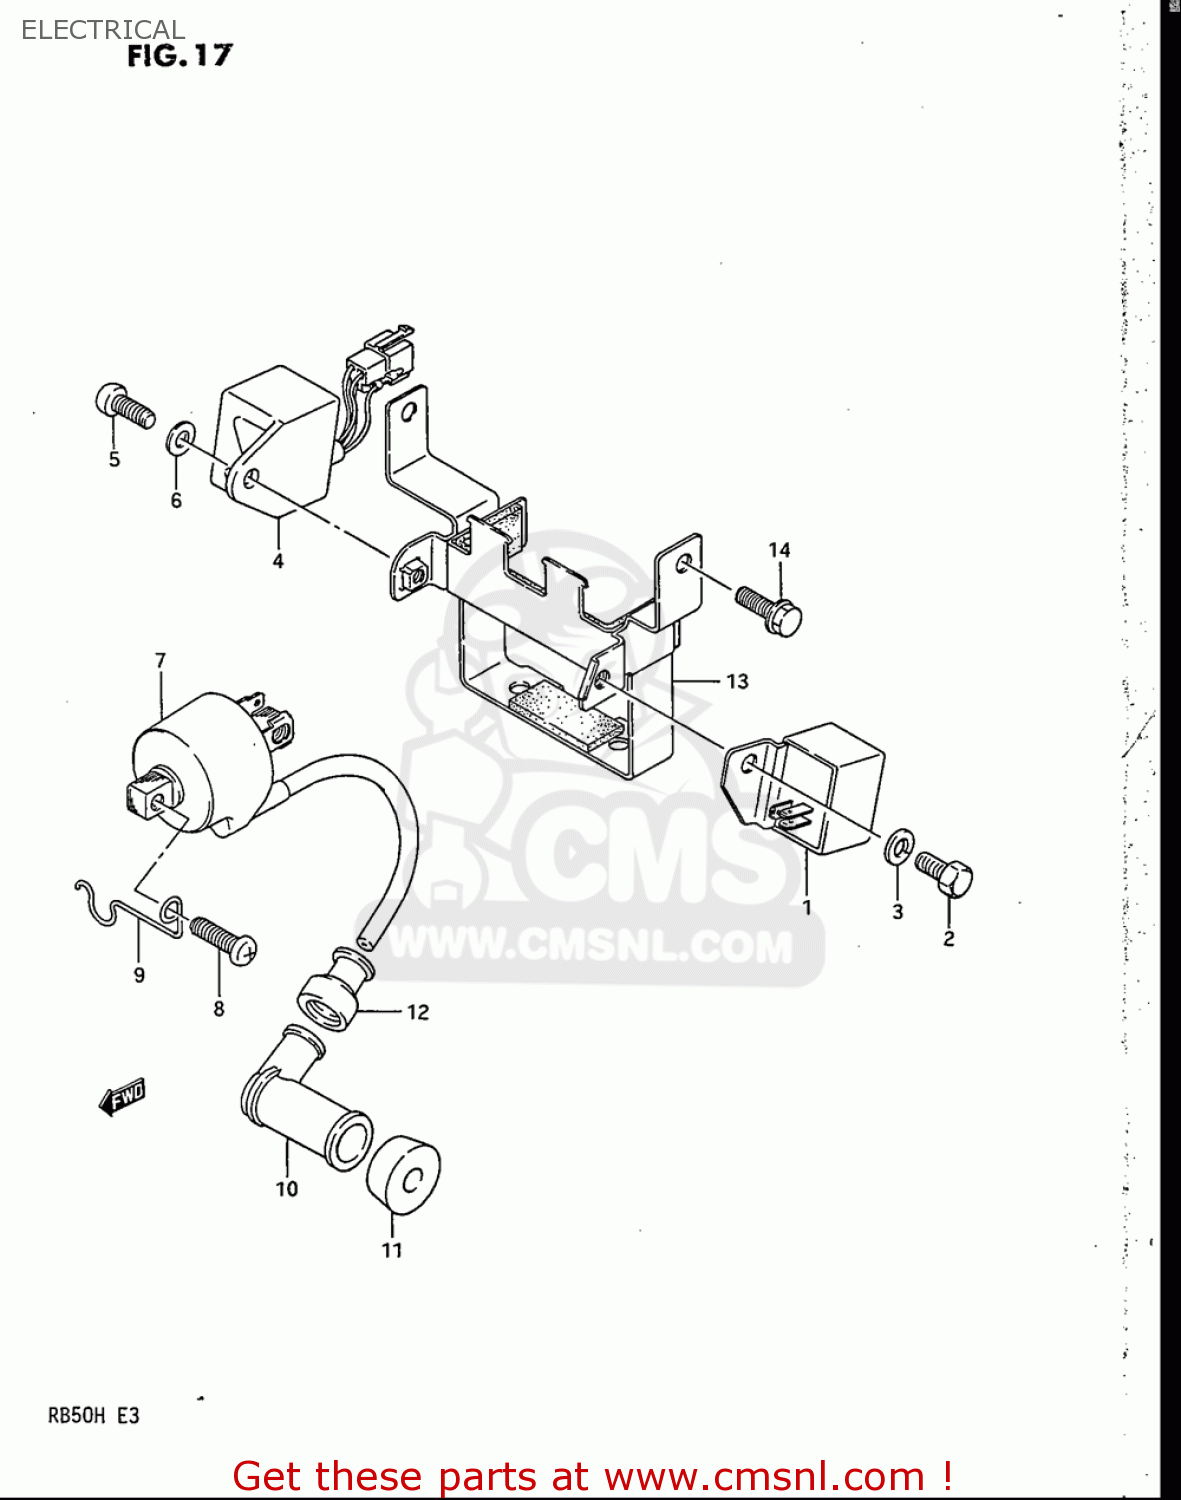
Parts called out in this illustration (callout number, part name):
1	RECTIFIER ASSY
2	BOLT
3	WASHER,LOCK
4	CDI UNIT
5	SCREW
6	WASHER
7	COIL ASSY,IGNITION NO.1
8	SCREW
9	GUIDE,CLUTCH CABLE
10	CAP,SPARK PLUG
11	SEAL,SPARK PLUG
12	SEAL,HIGH TENSION CORD
14	BOLT
